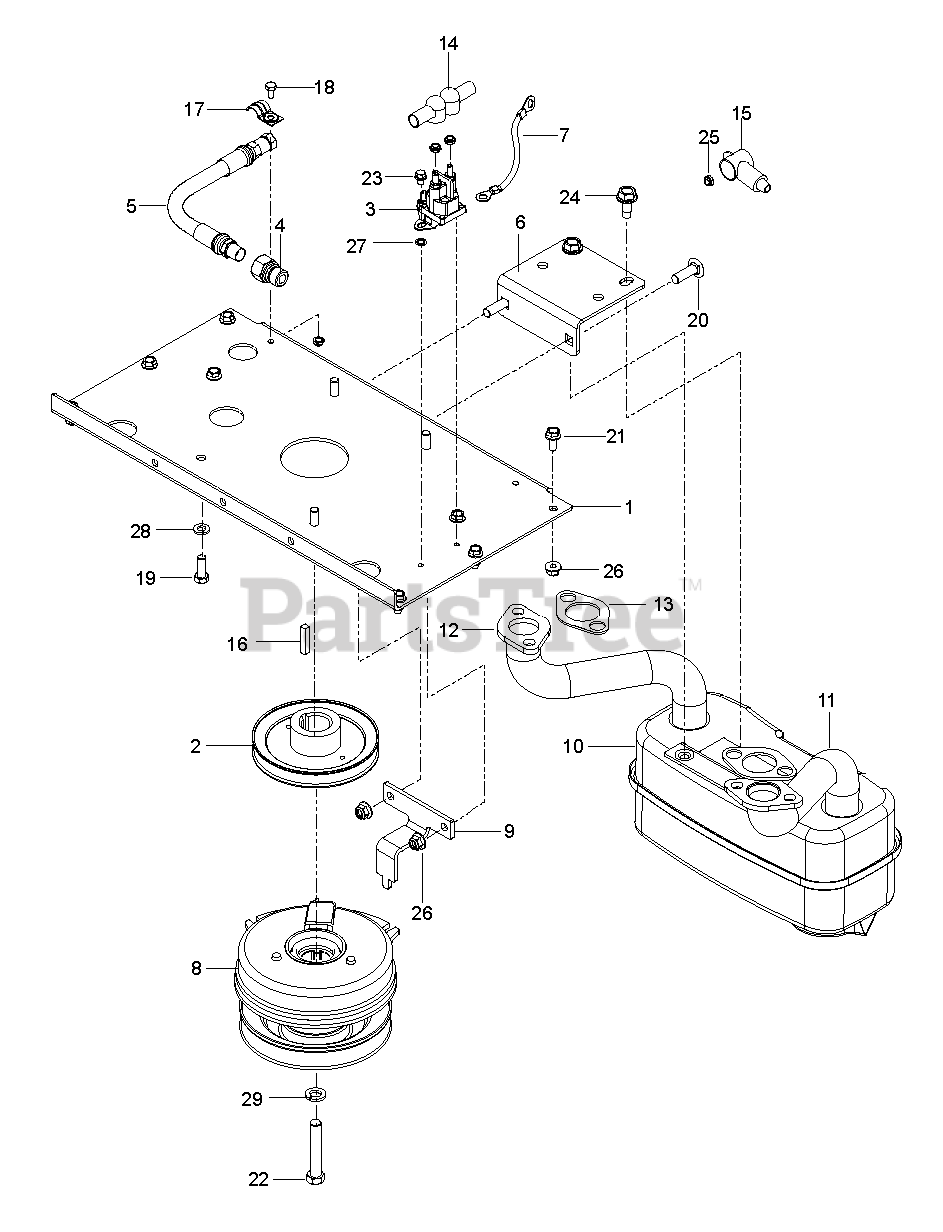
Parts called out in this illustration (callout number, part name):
1	PLATE.PNT.ENGINE.E-DIP
2	PULLEY, V, 1.125 BORE
3	SOLENOID.STARTER.BRASS.PLUNGER
4	ADAPTER, OIL DRAIN
5	HOSE.ASSEMBLY.OIL.DRAIN
6	BRKT, MUFFLER, BLK
7	CABLE POSITIVE
8	CLUTCH 200 FT LB
9	STOP, CLUTCH, BLACK
10	MUFFLER ASM TWIN
11	TUBE.EXHAUST.LH.FR961/FR730
12	CABLE POSITIVE
13	GASKET.EXHAUST.KAWASAKI
14	TERMINAL COVER
16	KEY, 1/4 SQ X 1 1/4
25	Hardware
26	NUT HEXAGON FLANGE 5/16-18 ST
27	WASHER 1/4 INT TOOTH
